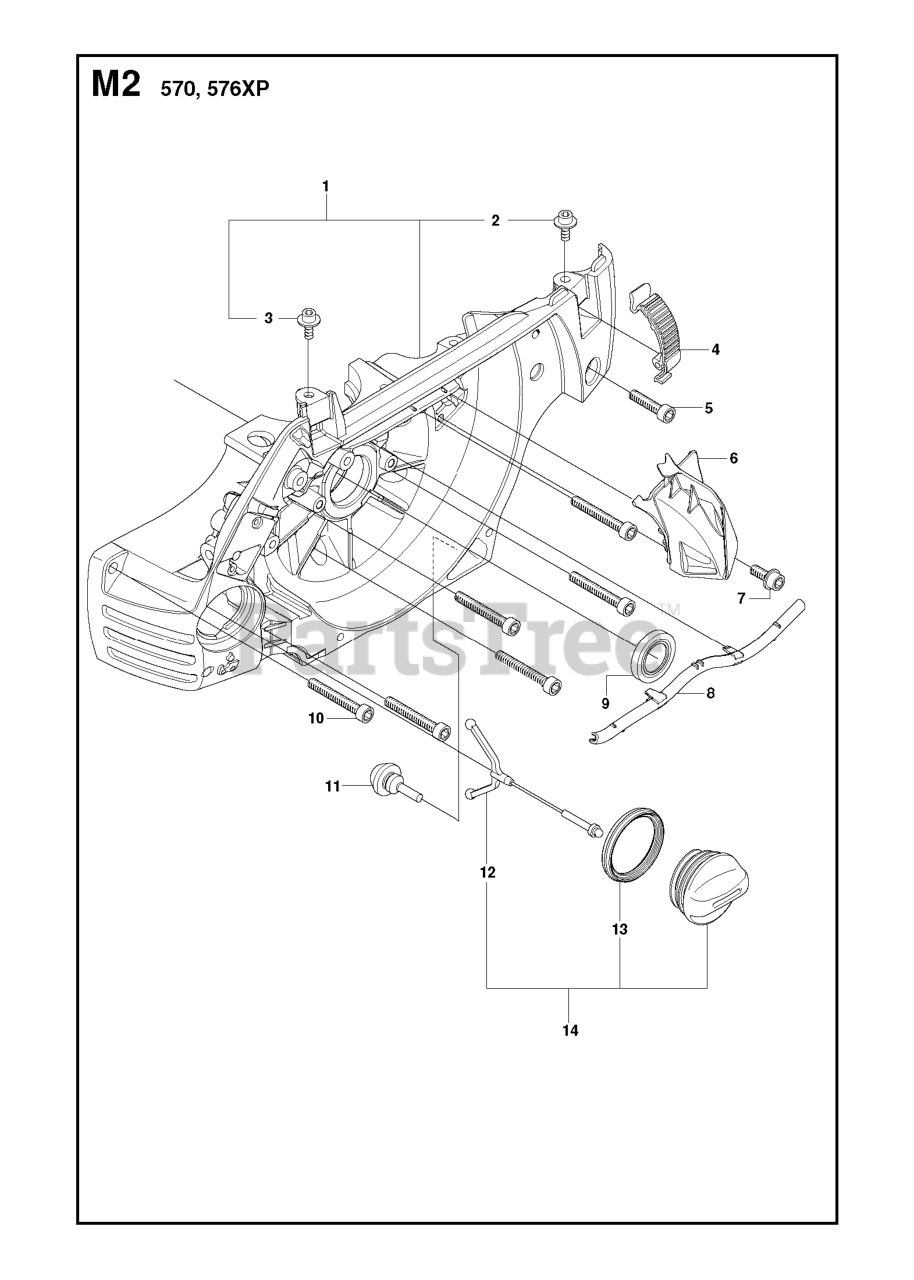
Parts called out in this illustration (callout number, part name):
1	CRANKCASE ASSY
1	RP CRANKCASE ASSEMBLY
2	SCREW IHSCM
3	SCREW IHSCM
4	CLIP GRAY
4	BUCKLE ORANGE
9	RADIAL SEAL
9	SEAL RING
14	TANK CAP
